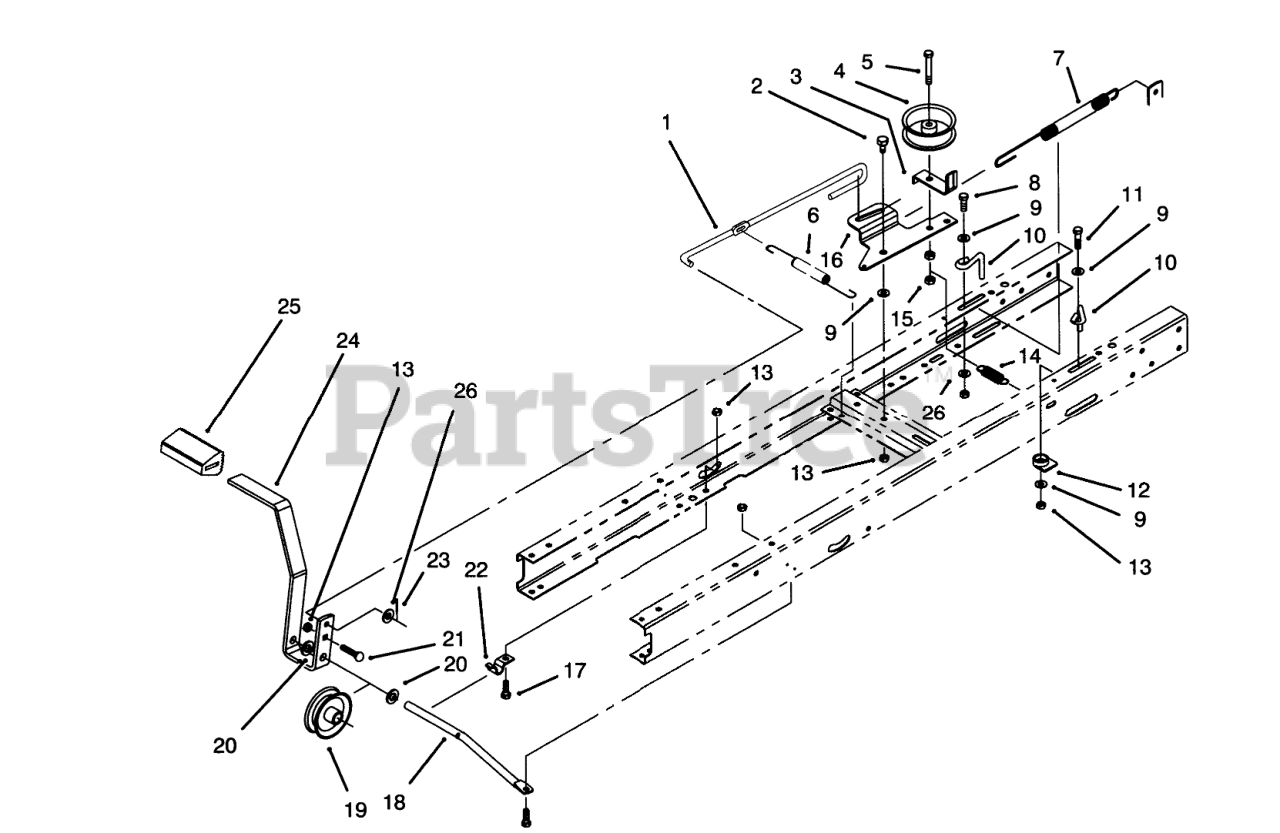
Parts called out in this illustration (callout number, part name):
1	ROD-CLUTCH/BRAKE
2	BOLT-SHOULDER
3	GUIDE-IDLER, BELT
4	Idler Pulley
5	SCREW-HH
6	SPRING-EXTENSION
7	BRAKE SPRING
8	SCREW-HH
9	WASHER-PIVOT
10	TRANS BELT GUIDE
11	SCREW-HH
12	GUIDE-CABLE
13	NUT-LOCK, NI
14	SPRING-EXTENSION
15	NUT-LOCK, NI
16	ARM-IDLER
17	SCREW-HH
18	ROD-PIVOT, PEDAL
19	PULLEY, CABLE
20	WASHER-FLAT
21	SCREW-CARR
22	CLAMP-PIVOT, SHIFT
23	PIN-COTTER
24	Pedal-Clutch/Brake
25	PAD-PEDAL
26	WASHER-PLAIN
